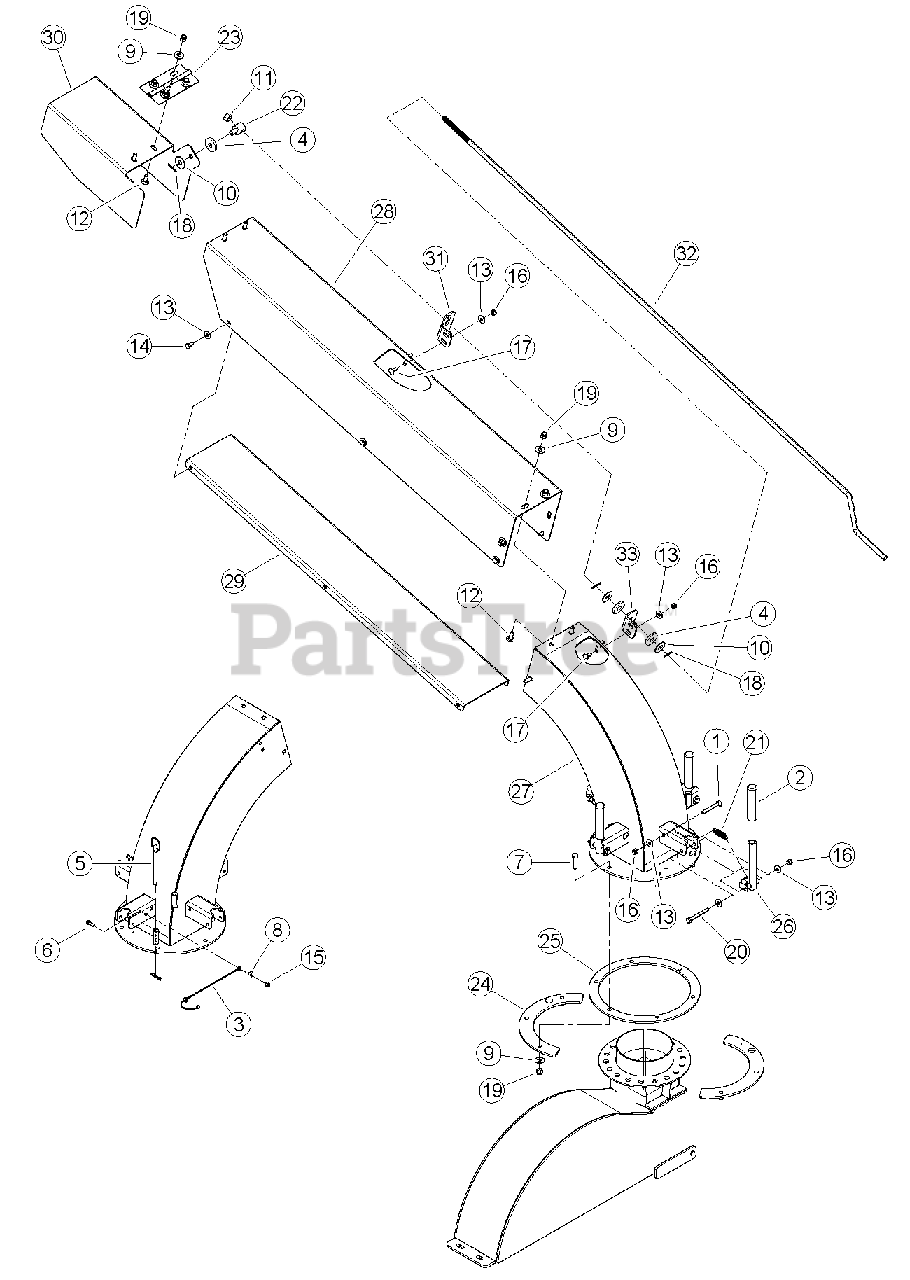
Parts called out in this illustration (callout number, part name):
1	BOLT, 5/16 X 2-1/2 CRG GR5 ZP
2	GRIP, TILT CONTROL
3	LANYARD, NYLON
4	WASHER, UHMW SPACER .515ID-1.50OD
5	PIN, 3/8 HITCH
6	BOLT, 1/4 X 3/4 HEX HD GR5 ZP
7	BOLT, 3/8 X 1-1/2 HEX HD GR5 ZP
8	WASHER, 1/4 FLAT ZP
9	WASHER, 3/8 FLAT ZP
10	WASHER, 1/2 FLAT ZP
11	NUT, 1/2 CENTERLOCK GRB ZP
12	BOLT, 3/8 X 1 CRG GR5 NC ZP
13	WASHER, 5/16 FLAT ZP
14	BOLT, 5/16 X 5/8 HEX HD GR5 ZP
15	NUT, 1/4 NE NYLOCK ZP
16	NUT, 5/16 NE NYLOCK ZP
17	BOLT, 5/16 X 3/4 CRG GR5 NC ZP
18	PIN, 1/8 X 1.00 COTTER ZP
19	NUT, 3/8 NE NYLOCK ZP
20	BOLT, 5/16 X 2-3/4 HEX HD GR5
21	SPRING, 1/2 X 2.00 LG ZP
22	PIVOT, HEIGHT ADJUSTMENT
23	HINGE, DISCHARGE CAP
24	RETAINER, DISCHARGE
25	SPACER, DISCHARGE CHUTE
26	WELDMENT, HANDLE
27	WELDMENT, DISCHARGE CHUTE
28	CHANNEL, DISCHARGE CHUTE
29	WELDMENT, DISCHARGE BOTTOM
30	CAP, DISCHARGE
31	STRIP, DISCHARGE
32	CRANK, DISCHARGE
33	BRACKET, DISCHARGE CRANK
